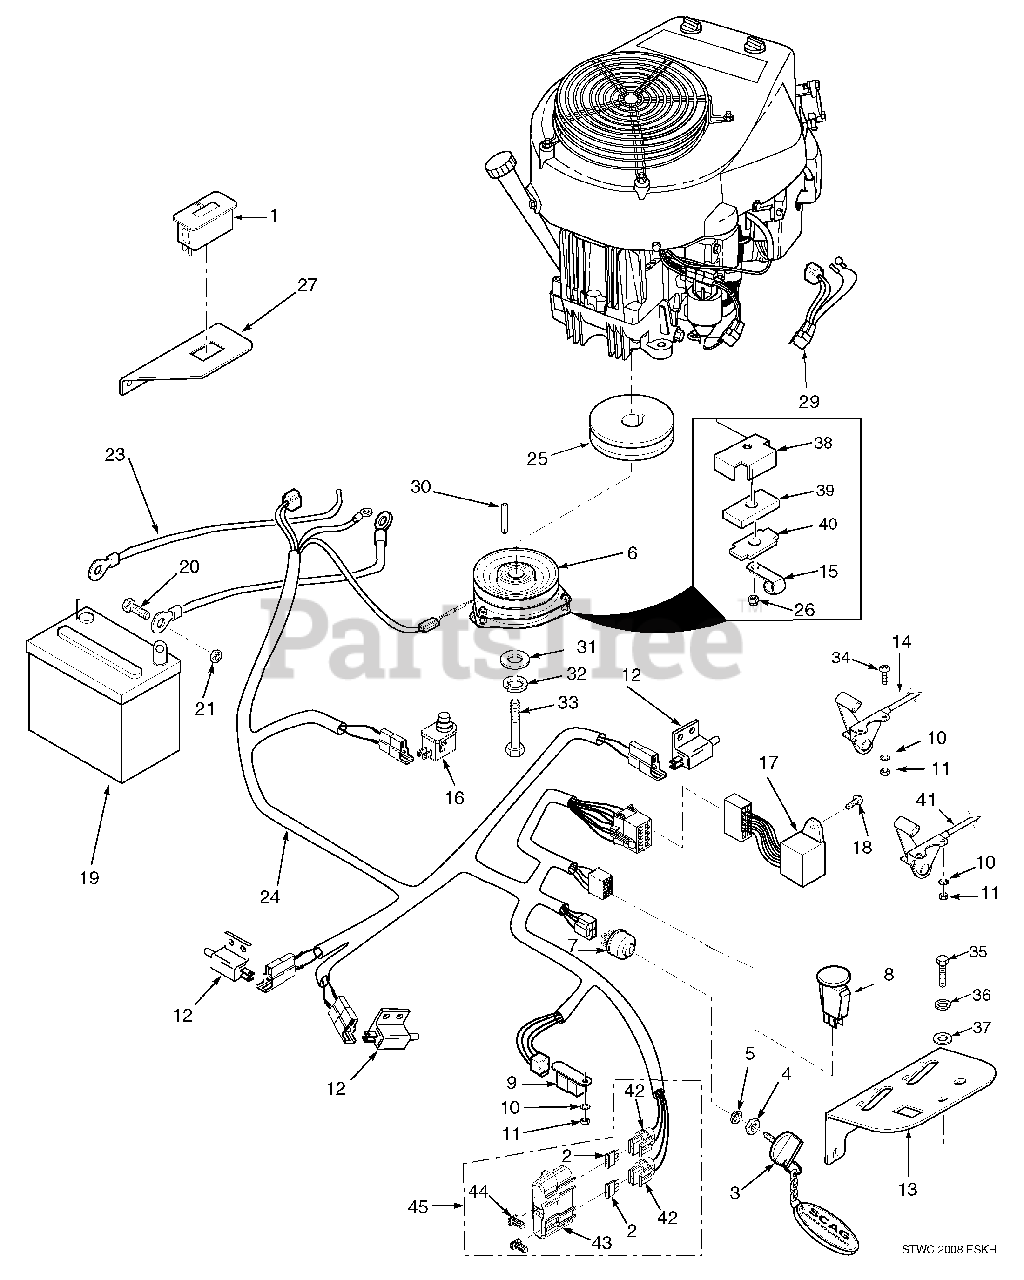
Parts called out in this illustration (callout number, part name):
1	Hourmeter
2	Fuse, 20 Amp
3	Key, Ignition
4	Nut, Hex 5/8-32
5	Lockwasher, 5/8" Internal
6	Electric PTO Clutch GT3.5
7	Switch, Ignition
8	Switch, PTO
9	Relay
10	Lockwasher, #10 External Tooth
11	Nut, Hex #10-32
12	Switch, N/O
13	Panel, Instrument
14	Choke Control
16	Switch, Seat
17	Module, Interlock
18	Screw, #10-32 x .5" Phillips Head
19	Battery
20	Bolt, Hex Hd. 1/4-20 x .5"
21	Nut, Hex 1/4-20
22	Cable, Battery Black (negative)
23	Cable, Battery Red (positive)
24	Wiring Harness, Main
25	Pulley, 5.45" OD x 1.125" Bore
26	Nut, Elastic Stop 5/16-18 Key
27	Mounting Bracket, Hour Meter
28	Screw, #10-32 x 1.5" Phillips Head
29	Adapter, Wiring Harness
30	Key, 1/4 x 1/4 x 3-1/4"
31	Flatwasher, 7/16 (.469 x 1-3/4" x 1/4")
32	Lockwasher, 7/16"
33	Bolt, Hex Hd. 7/16-20 x 2-1/4" UNF
34	Screw, #10-32 x 3/4"
35	Bolt, Hex Hd. 5/16-18 x 3/4"
36	Lockwasher, 5/16"
37	Flatwasher, 5/16 (.375 x .875 x .083")
38	Backing Plate
39	Rubber Pad, Clutch Stop
40	Plate, Backing
41	Throttle Control
42	Fuse Holder
43	Cover, Sealed Double
44	Clip, Wire
45	Double Fuse Assembly, Sealed
